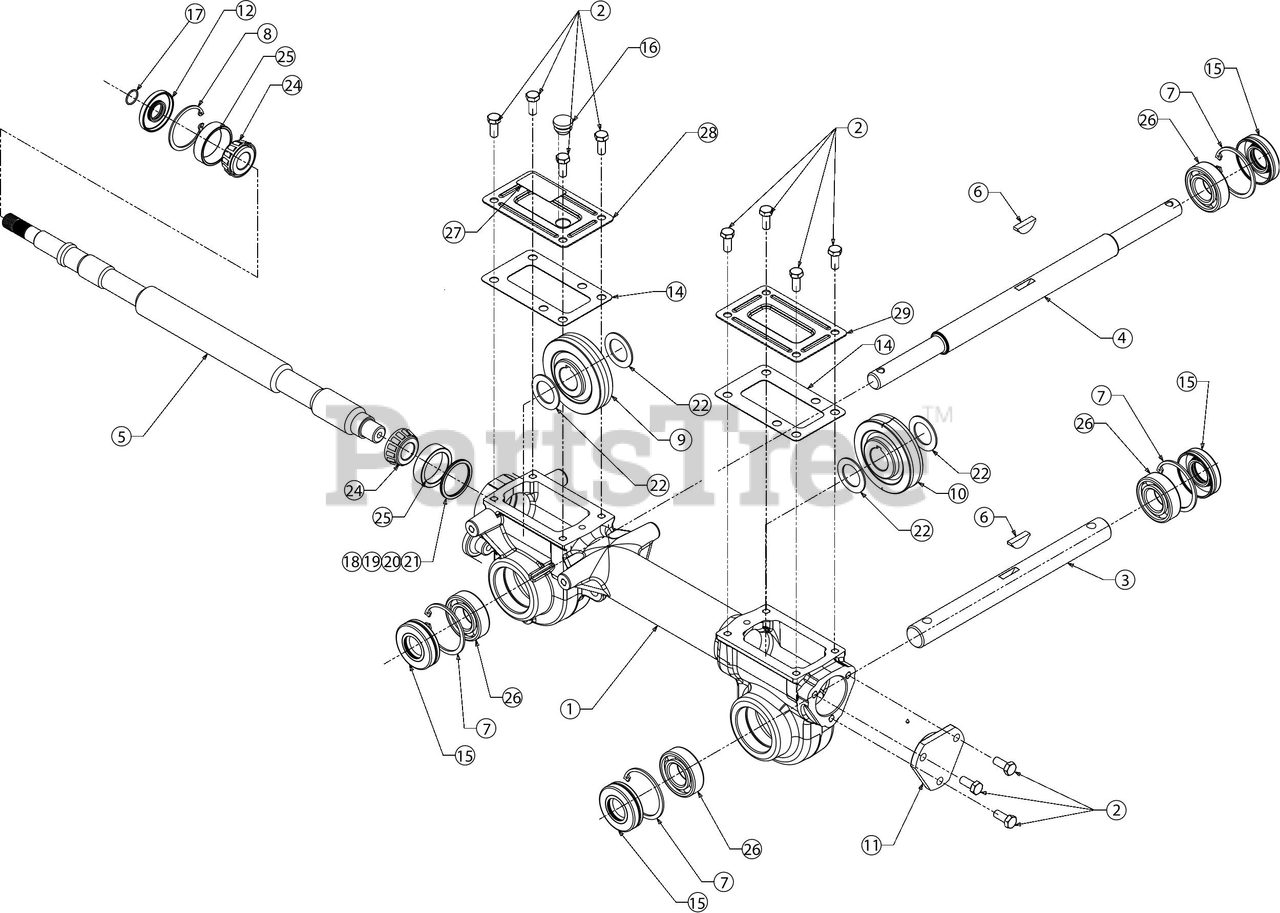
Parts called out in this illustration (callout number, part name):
1	TRANSMISSOIN HOUSING
2	SCREW 5/16-18 x .75 GR5
3	TILLER SHAFT
4	WHEEL SHAFT
5	DRIVE SHAFT
6	KEY-HI PRO .25 x 1
7	RETAINING RING
8	RETAINING RING
9	WORM GEAR (RH) 61T
10	WORM GEAR (LH) 30T
11	BEARING COVER
12	OIL SEAL .750 SHF x 1.783
14	GEAR HOUSING GASKET
15	OIL SEAL 1.00 SHF x 2.00 BORE
16	RUBBER OIL PLUG
17	WIRE RING
18	FLAT WASHER 1.500X1.750X.062
19	FLAT WASHER 1.500X1.750X.005
20	FLAT WASHER 1.500X1.750X.030
21	FLAT WASHER 1.500X1.750X0.010
22	WASHER 1.010X1.560X.060
24	BEARING CONE
25	BEARING CUP
26	BALL BEARING
28	TRANSMISSION COVER
29	TRANSMISSION COVER
